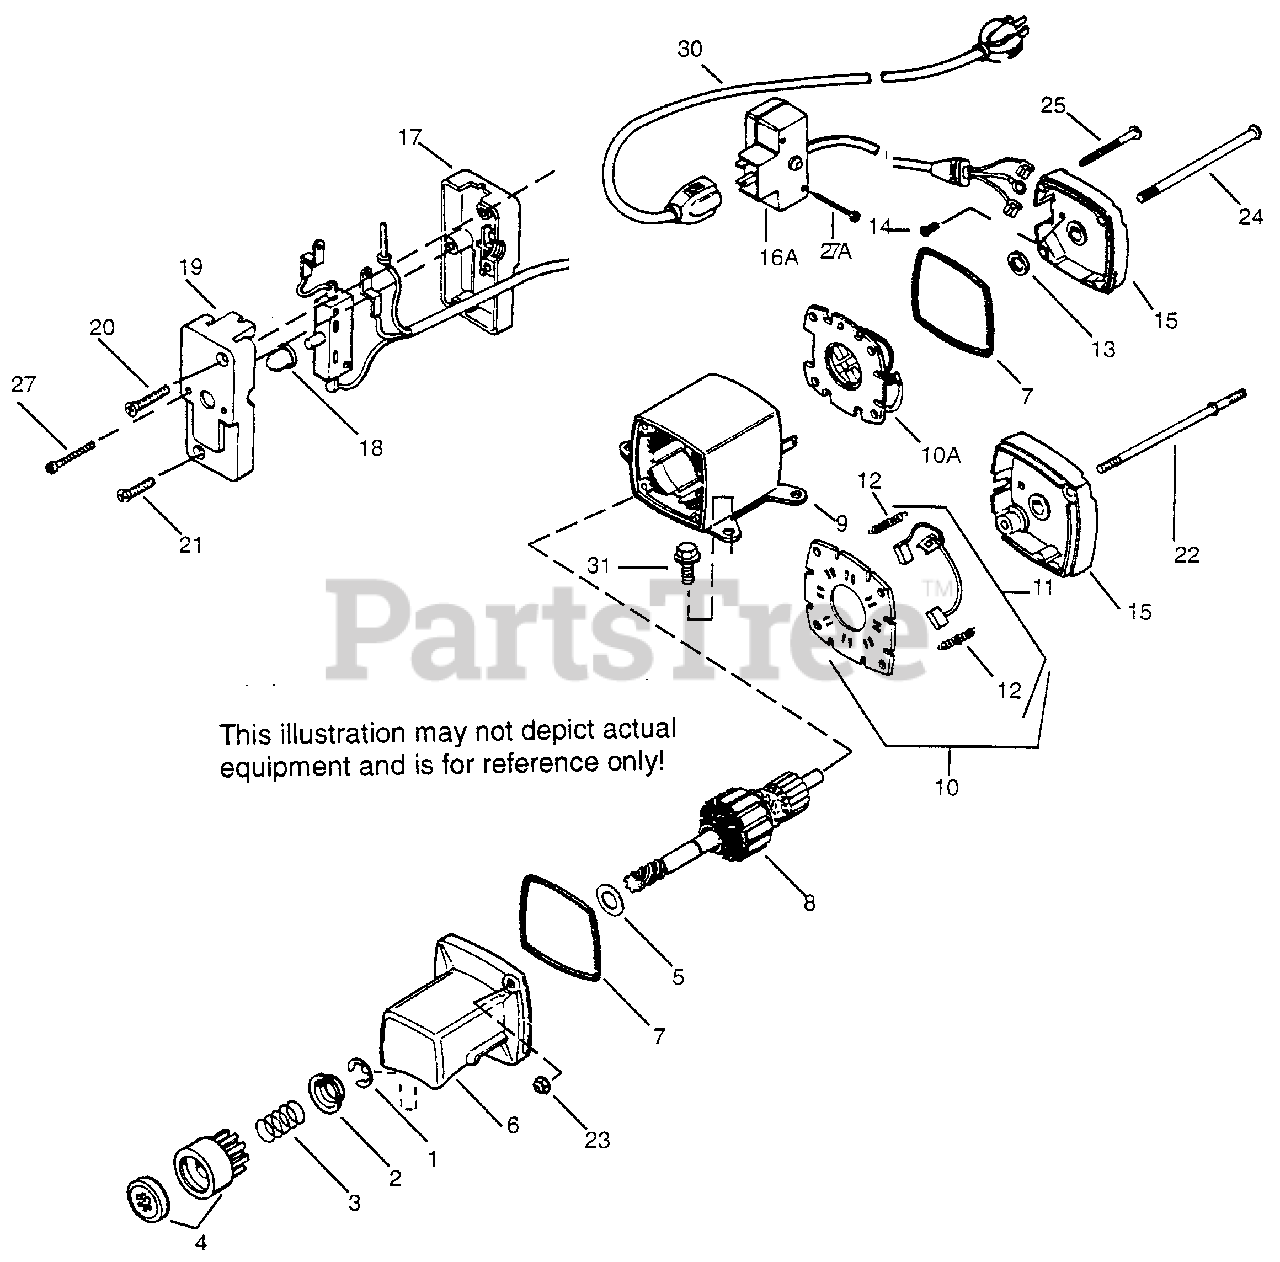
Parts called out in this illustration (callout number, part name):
1	Retainer Ring
2	Spring Retainer
3	Anti-drift Spring
4	Nut & Gear
6	Drive End Cap Ass'y.
8	Armature
9	Housing Ass'y.
10	Brush Card Ass'y. (Incl. 11)
11	Brush & Spring Kit (Incl. 12)
12	Brush Spring
13	Thrust Washer
14	Ground Screw
15	Commutator End Cap Ass'y.
16	Switch Box Ass'y. (Incl. 17 thru 21)
17	Switch Box
18	Switch Button
19	Switch Box Cover
20	Screw, 6-32 x 1"
21	Screw, 6-32 x 3/4"
22	Case Bolt
23	Lock Nut
